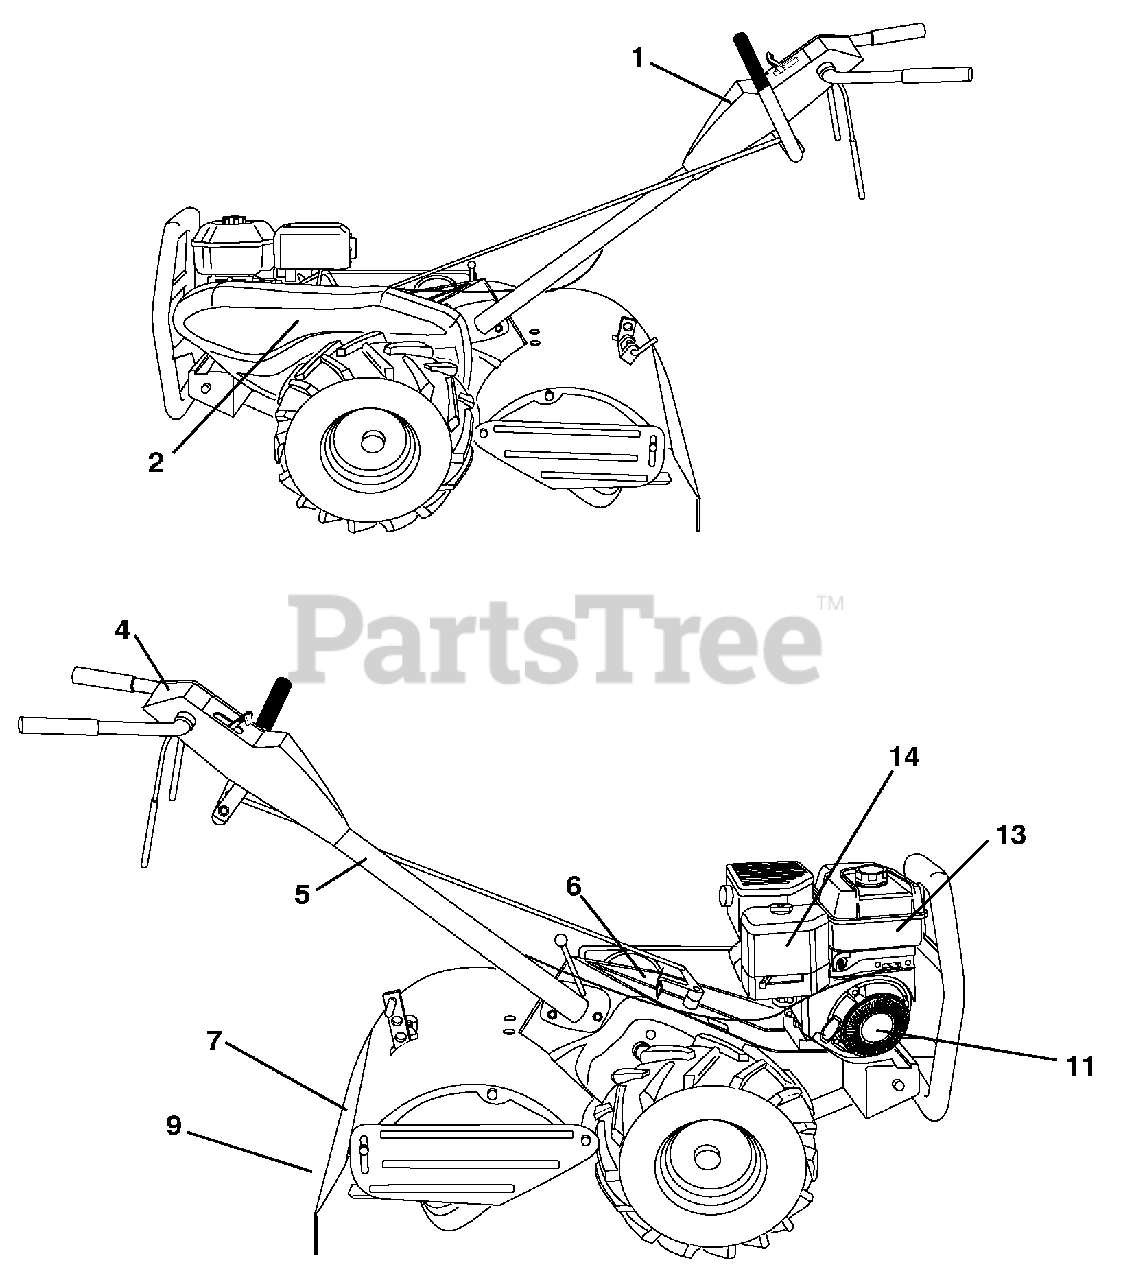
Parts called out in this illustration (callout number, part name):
1	Decal, CNTRL PNL
2	Decal, Decal, Blt Grd
4	Decal, Instruction, Tilling
5	Decal, Hand Placement
6	Decal, Shift Indicator
7	Decal, Caution
9	Decal, Warning, Rotating Tines
11	Decal, Rewind
13	Decal, B&S Tank
14	Decal, B&S, Air Cleaner
14	Manual, Operator's, English/French
14	Manual, Repair Parts, English/French
